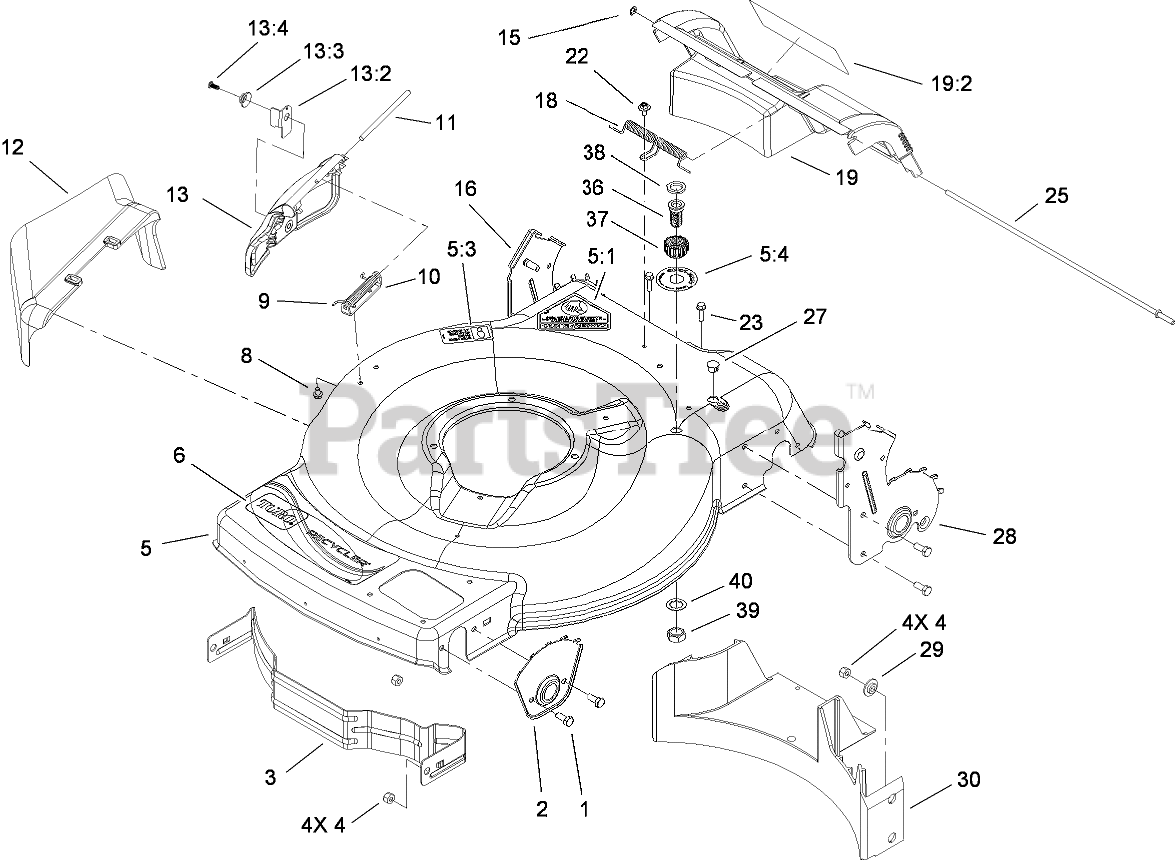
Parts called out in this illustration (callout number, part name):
1	SCREW-HH
2	Plate-HOC, Front
3	Baffle-Front
4	NUT-LOCK, NI
5	BBC HOUSING ASM
5:1	DECAL-DANGER
5:3	DECAL-PLACEMENT, FOOT
5:4	DECAL-PORT, WASHOUT
6	DECAL-RECYCLER (RWD)
8	SCREW-HWH
9	SPRING-TORSION
10	BRACKET-COVER
11	ROD-COVER
12	CHUTE-DISCHARGE, SIDE
13	DISCHARGE DOOR ASM
13:2	LATCH-DOOR
13:3	CAP-DOOR
13:4	SCREW-PLASTITE
15	NUT-PUSH
16	8 INCH RH HOC PLATE ASM
18	Spring-Door, Rear
19	REAR DOOR ASM
19:2	DECAL-WARNING
22	SCREW AND WASHER ASM
23	SCREW-HWH
25	Rod-Pivot, Rear Door
27	Plug-Dome
28	8 INCH LH HOC PLATE ASM
29	Washer-Stepped
30	Baffle-Rear
36	PORT-WASHOUT
37	COUPLING-HOSE, WASHOUT PORT
38	WASHER-SEAL, WASHOUT PORT
39	NUT-JAM
40	WASHER-TOOTH, INTERNAL
